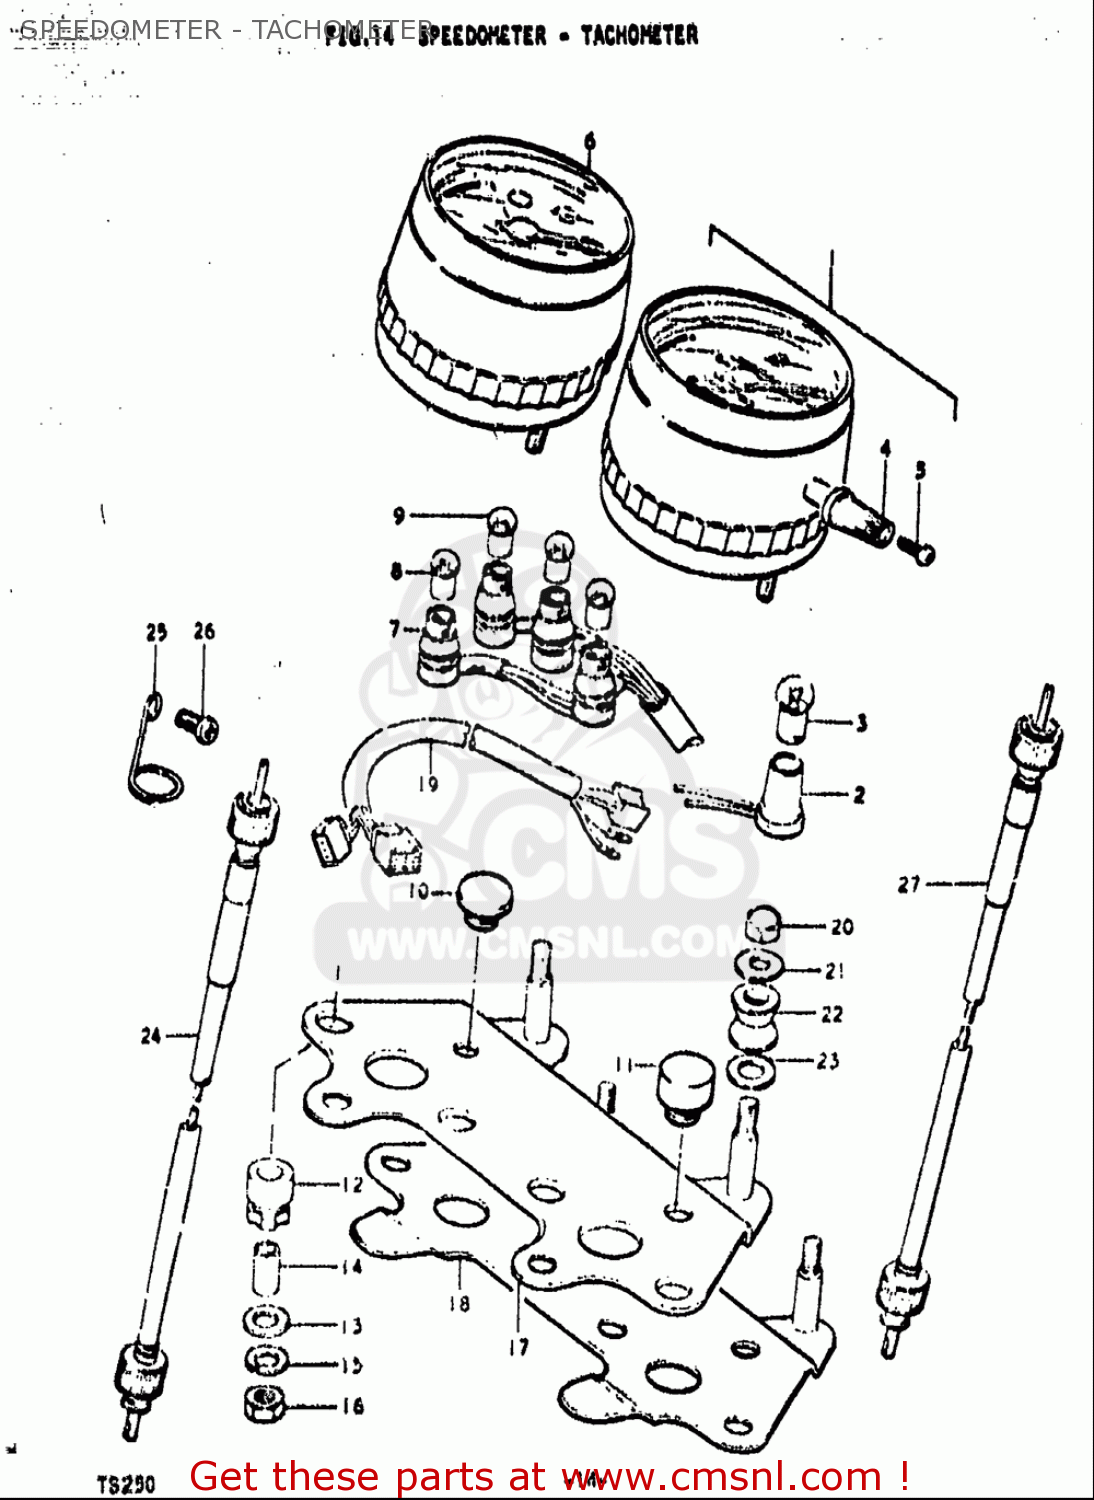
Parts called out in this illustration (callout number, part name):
2	SOCKET,METER
3	BULB(6V/3W)
5	SCREW(2X6)
8	BULB(6V/3W)
9	BULB(6V1.7W,STANLEY,A61A)
10	CUSHION,METER NO.1
13	WASHER(6.5X18X1.6)
15	WASHER,LOCK
16	NUT
20	NUT
21	WASHER(6.5X18X1.6)
22	CUSHION
23	WASHER
24	CABLE ASSY,TACHOMETER
25	CLIP
26	SCREW
27	CABLE ASSY,SPEEDOMETER
